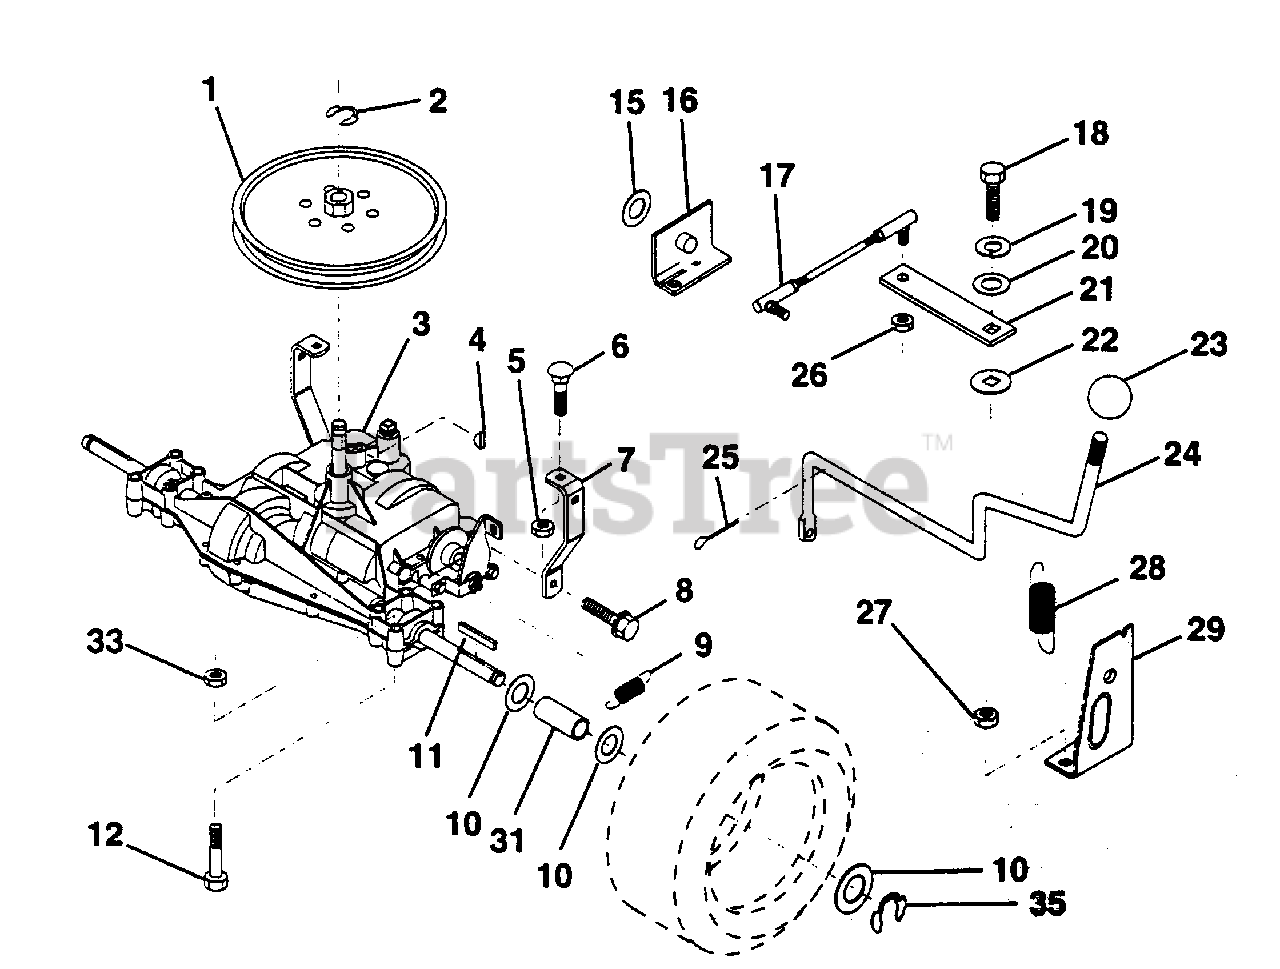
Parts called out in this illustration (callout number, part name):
1	Pulley (AYP part number)
2	Ring, Retainer (AYP part number)
3	Transaxle, Dana Model No. 4360-79 (AYP part number)
4	Key, Woodruff #9 (AYP part number)
5	Nut,Lock Hex w/Ins 5/16-18 (AYP part number)
6	Bolt, Carriage 5/16-18 UNC x 3/4
7	Strap, Torque (AYP part number)
8	Screw 5/16-18 x 3/4
9	Spring, Brake (AYP part number)
10	Washer 25/32 x 1-1/4 x 16 Gauge (AYP part number)
11	Key, Square (AYP part number)
12	Bolt, Hex, Fin. 3/8-16 Unc x 2-3/4 (AYP part number)
15	Washer 17/32 x 1 x 16 Gauge (AYP part number)
16	Support Handle Shift, LH (AYP part number)
17	Link, Shift (AYP part number)
18	Bolt, Hex, Fin. 1/4-28 UNF x 3/4 Grade 8 (AYP part number)
19	Washer, Lock 1/4 (AYP part number)
20	Washer 9/32 x 3/4 x 10 Gauge (AYP part number)
21	Arm, Shift (AYP part number)
22	Washer, Shift Plate (AYP part number)
23	Knob, Duckhead (AYP part number)
24	Rod Assembly, Shift (AYP part number)
25	Pin, Cotter 1/8 x 1 (AYP part number)
26	Locknut 5/16-24 UNF (AYP part number)
27	Nut, Hex, Keps 5/16-18 (AYP part number)
28	Extension, Spring (AYP part number)
29	Support Handle Shift, RH (AYP part number)
31	Spacer Split (AYP part number)
33	Nut, Lock Hex w/Wsh 3/8-16 (AYP part number)
35	E-Ring (AYP part number)
